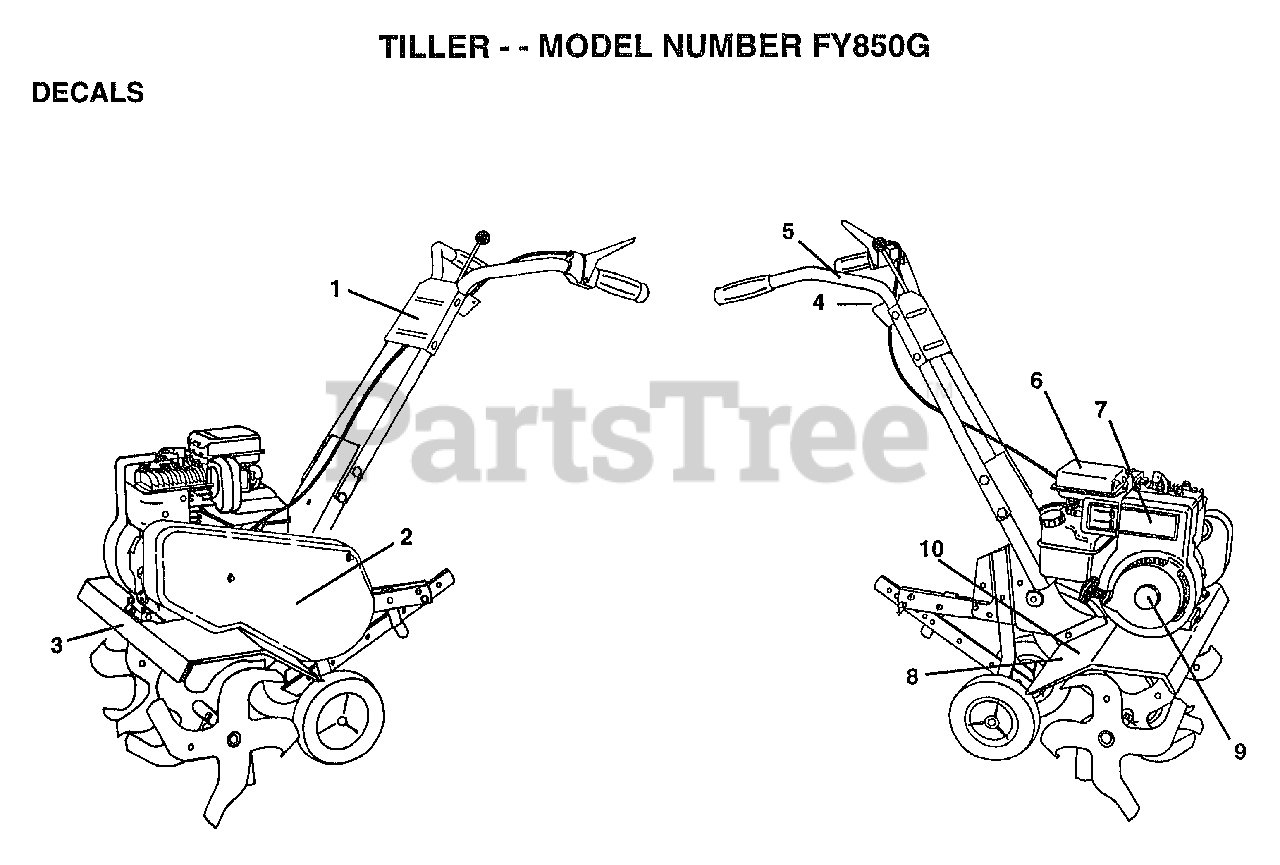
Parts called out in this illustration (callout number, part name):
1	DECAL HANDLE BRKT
2	DECAL.BELT.GUAR
3	DECAL TINE SHIELD
4	DECAL REVERSE
5	DECAL TI
6	DECAL TI
7	DECAL, BRIGGS & STRATTON
10	DECAL.CAUTION
